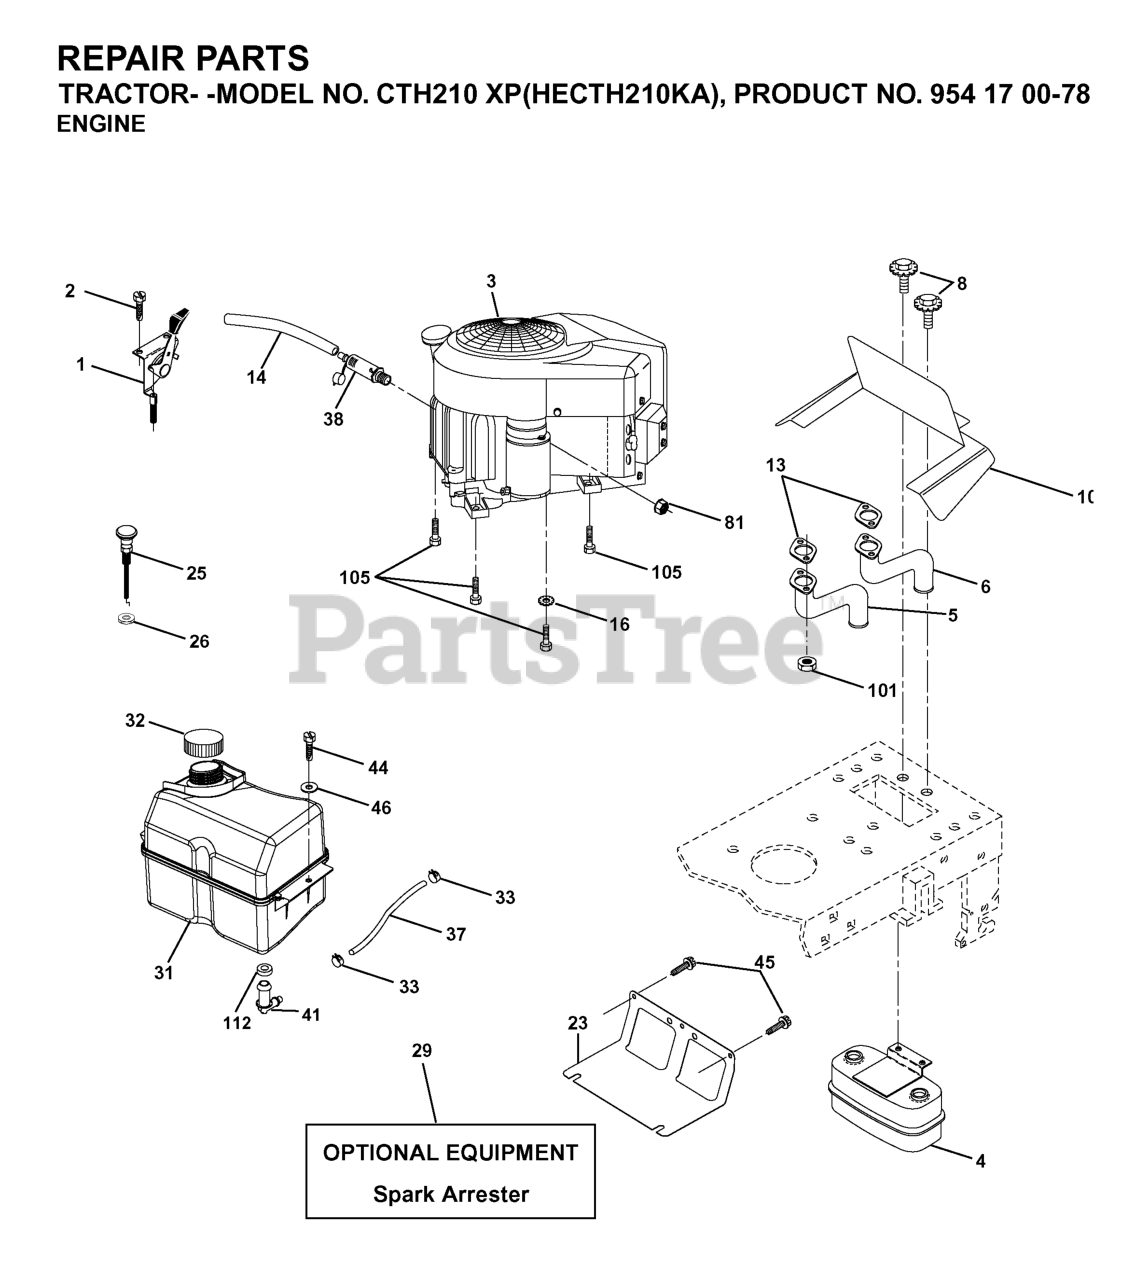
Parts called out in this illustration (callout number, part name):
1	CONTROL, THROTTLE
2	SCREW
4	MUFFLER.TWIN.CYL.LOW.TONE
5	TUBE EXHAUST LH
6	EXHAUST.TUBE.RH.KAWA
8	BOLT.5/16-18UNCX3/4 W/SEMS.BLK
10	RP SHIELD HEAT MUFFLER
14	TUBE, DRAIN OIL ASM.
16	LOCKWASHER
23	SHIELD.BROWNING.DBR.GUARD
25	CHOKE CONTROL
26	Nut Keps 3/8 - 24 UNF
29	KIT.SPARK ARRESTOR 794945 B&S
31	TANK FUEL
32	FUEL CAP
33	HOSE CLAMP
37	LINE.FUEL.20
41	STEM FUEL TANK
44	SCREW HEXWSHR 1/4-20X3/4
45	SCREW, 3/8-16X3/4
81	NUT
101	FLANGE NUT
105	SCREW 3/8-16X1
112	BUSHING OUTLET T
